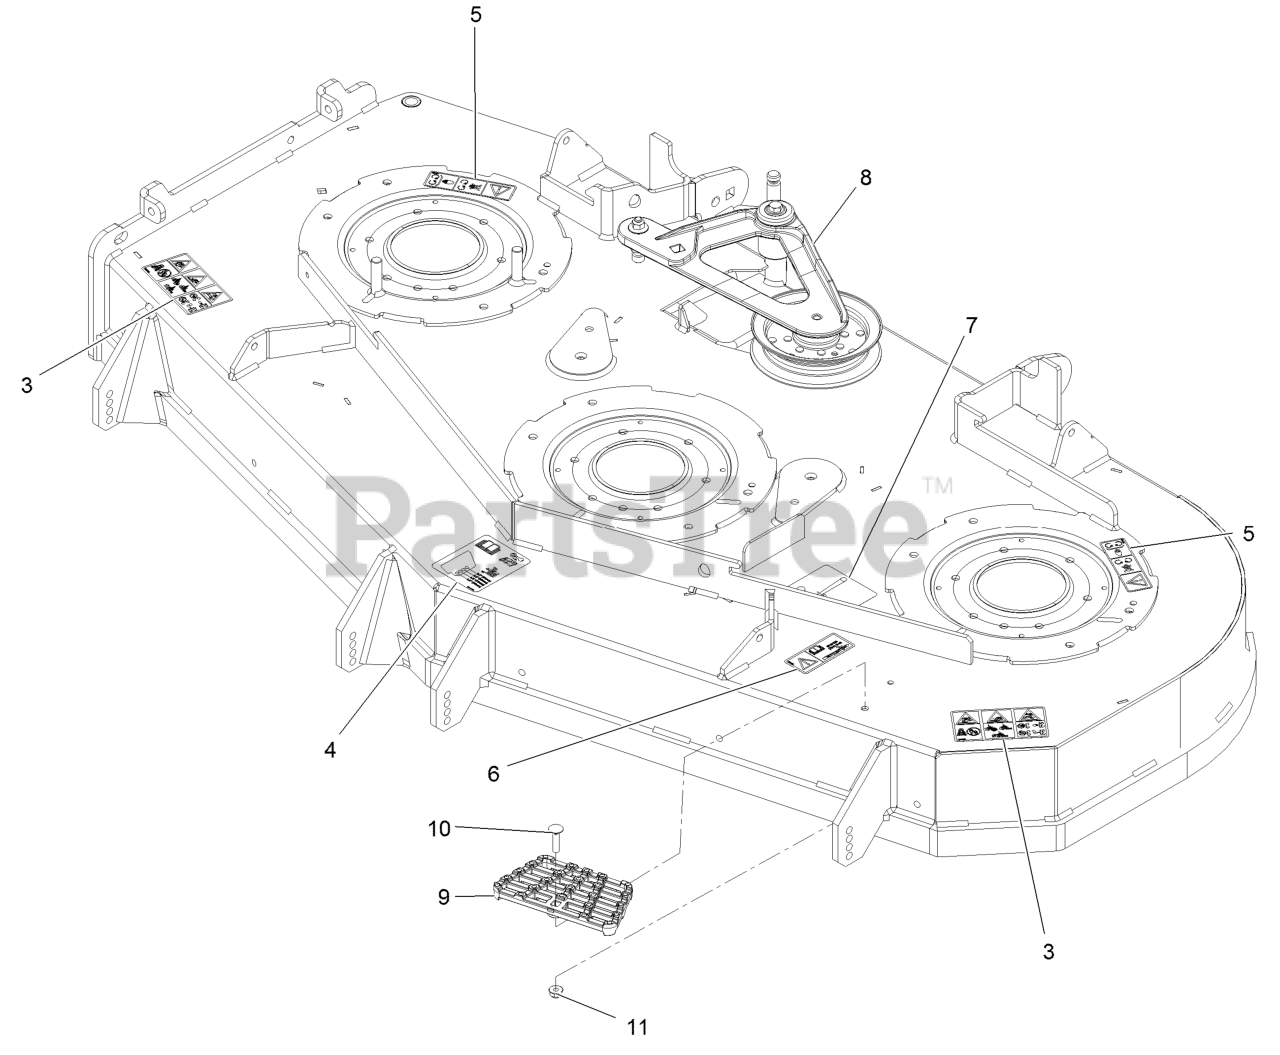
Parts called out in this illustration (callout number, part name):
3	DECAL-DANGER THROWN OBJECTS
4	DECAL-ROLLER, ANTI-SCALP
5	DECAL-COVER, MISSING
6	DECAL-BOLT TORQUE
7	DECAL-BELT ROUTING
8	DECK IDLER ASM
9	STEP-DECK
10	Bolt-Carriage 5/16-18 X 1 1/4
11	NUT-HF, NI
